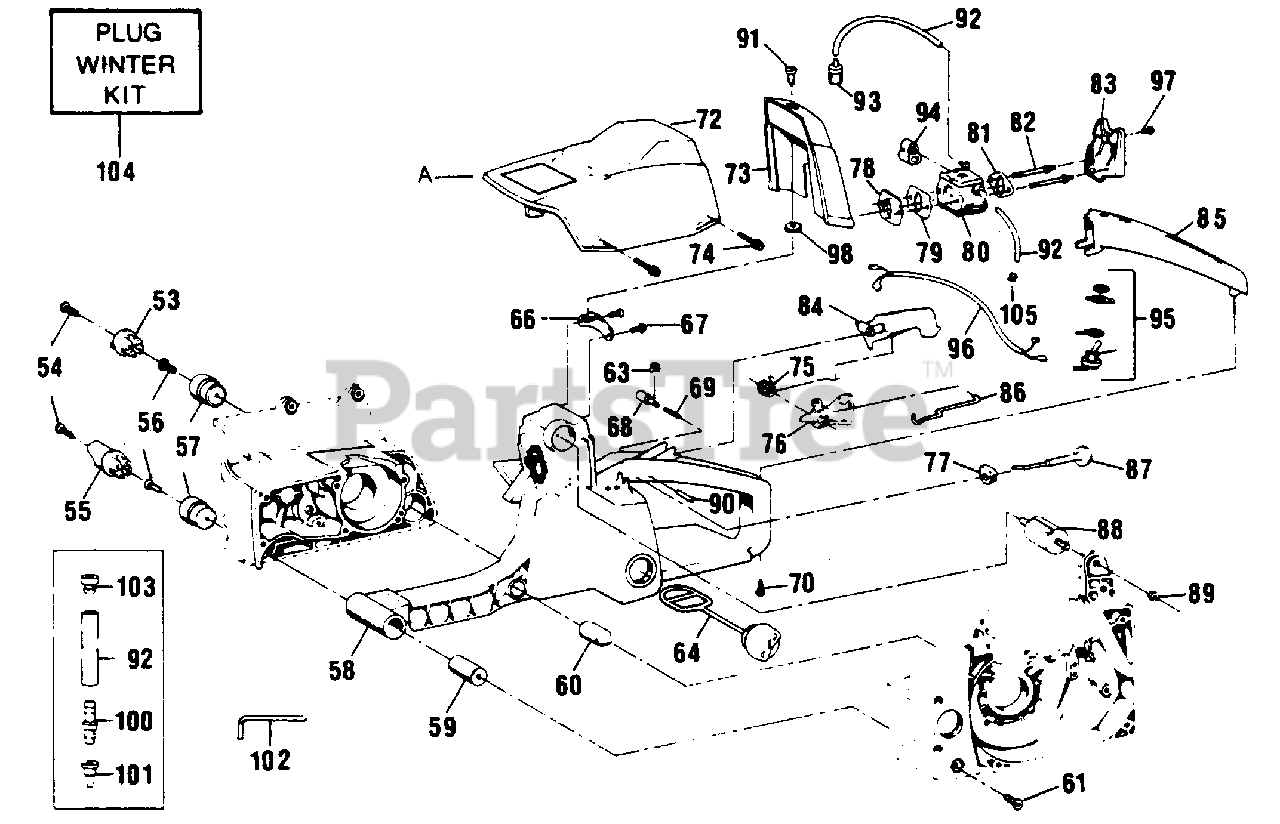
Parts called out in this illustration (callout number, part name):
53	Retainer Mount
55	Chain Catcher Retainer
57	Lower Isolator
58	Rear Handle & Fuel Tank
59	Cylindrical Mount
60	Isolator Limiter
63	"C" Clip
64	Fuel Cap Ass'y. (Inc. "O" Ring)
68	Throttle Lock
69	Throttle Lock Spring
72	Cylinder Shield
73	Carb. Cover
75	Trigger Latch Spring
76	Throttle Trigger
79	Gasket Set
80	CARBURETTOR
81	Air Filter Plate
82	Carb. Mounting Stud
83	Air Filter Ass'y. (Inc. #97)
84	Throttle Lockout
85	Ignition Module, MINI STD D100
86	Throttle Wire
87	Choke Knob
88	Left Isolator Mount
90	Dowel Pin
92	Line Kit
93	Fuel Filter Ass'y
95	Switch Kit
96	Lead Wire Ass'y
100	Vent Fitting
101	Check Valve
102	Hex Key
103	Vent Plug
104	Plug Winter Kit
A	Decal-Instructions Fr./Eng.
